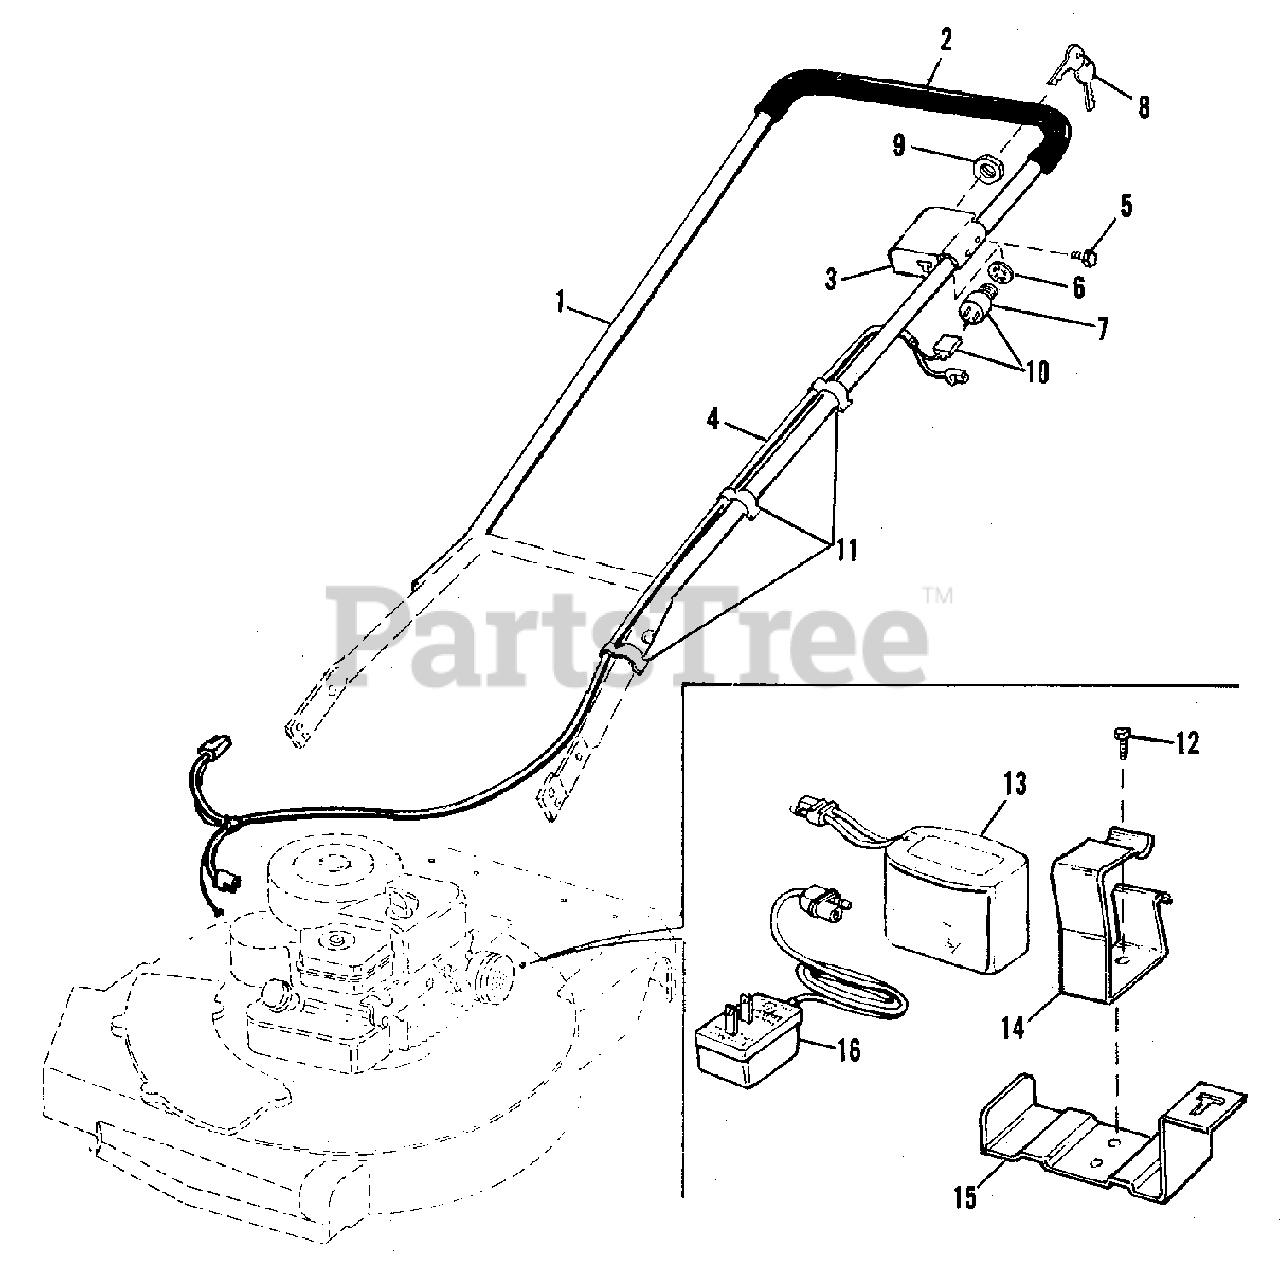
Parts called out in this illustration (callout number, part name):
1	HANDLE, Upper
2	TUBING, Handle
3	BRACKET, Switch Mounting
5	SCREW, Hex, 1/4-20 x 3/8
6	WASHER, Lock, 9/16
7	SWITCH, Starter
9	NUT, Hex, Special
10	SWITCH & HARNESS
11	CLAMP, Handle Cable
12	SCREW, Pan, 10-24 x 3/8
14	CLIP, Spring, Battery
15	SUPPORT, Battery
16	CHARGER, Battery
